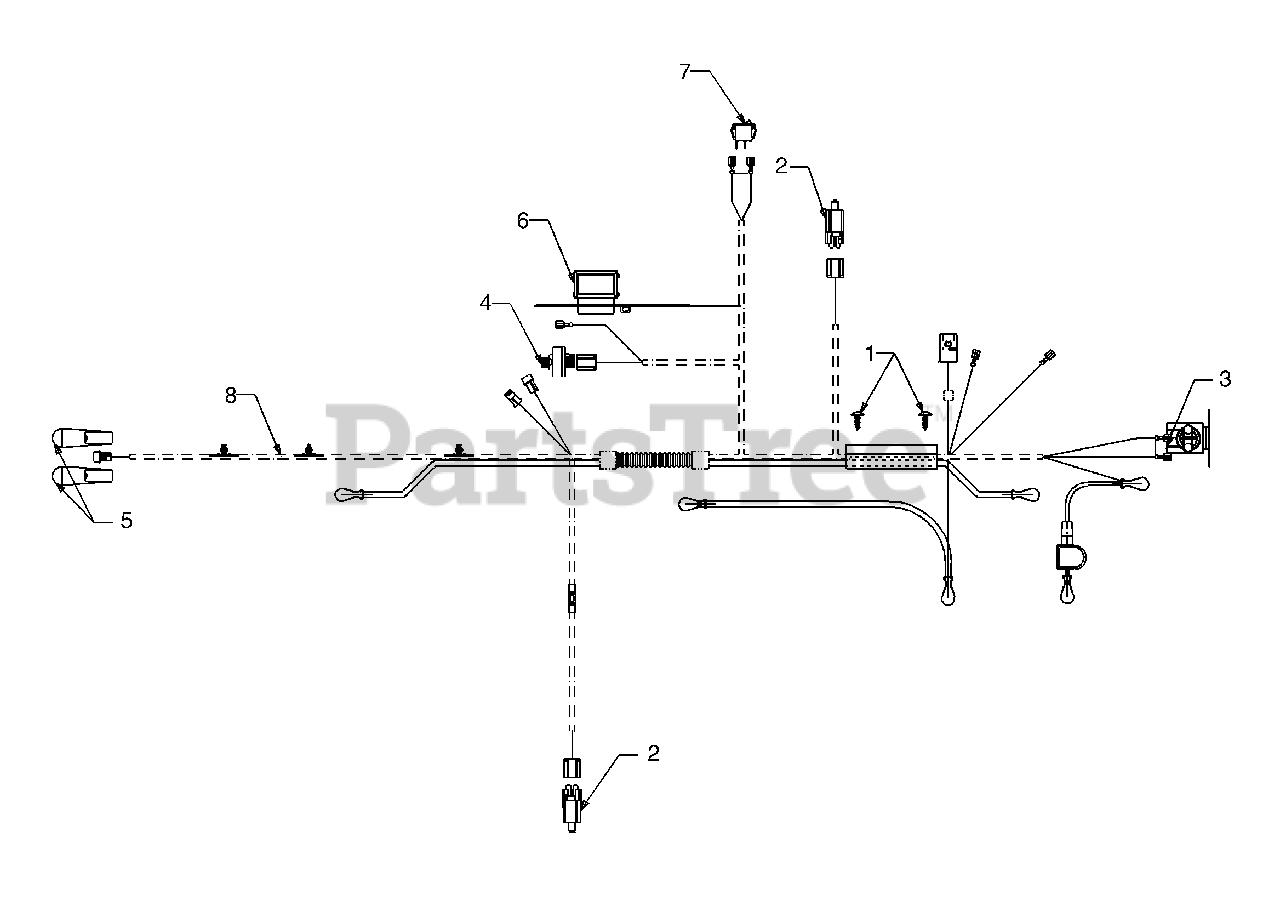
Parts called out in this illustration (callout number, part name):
1	Ratchet
2	Safety Switch
3	Solenoid
4	Ignition Switch
5	Bulb (Headlight)
6	Ammeter
7	Light Switch
8	Wire Harness w/Lt./Amp
